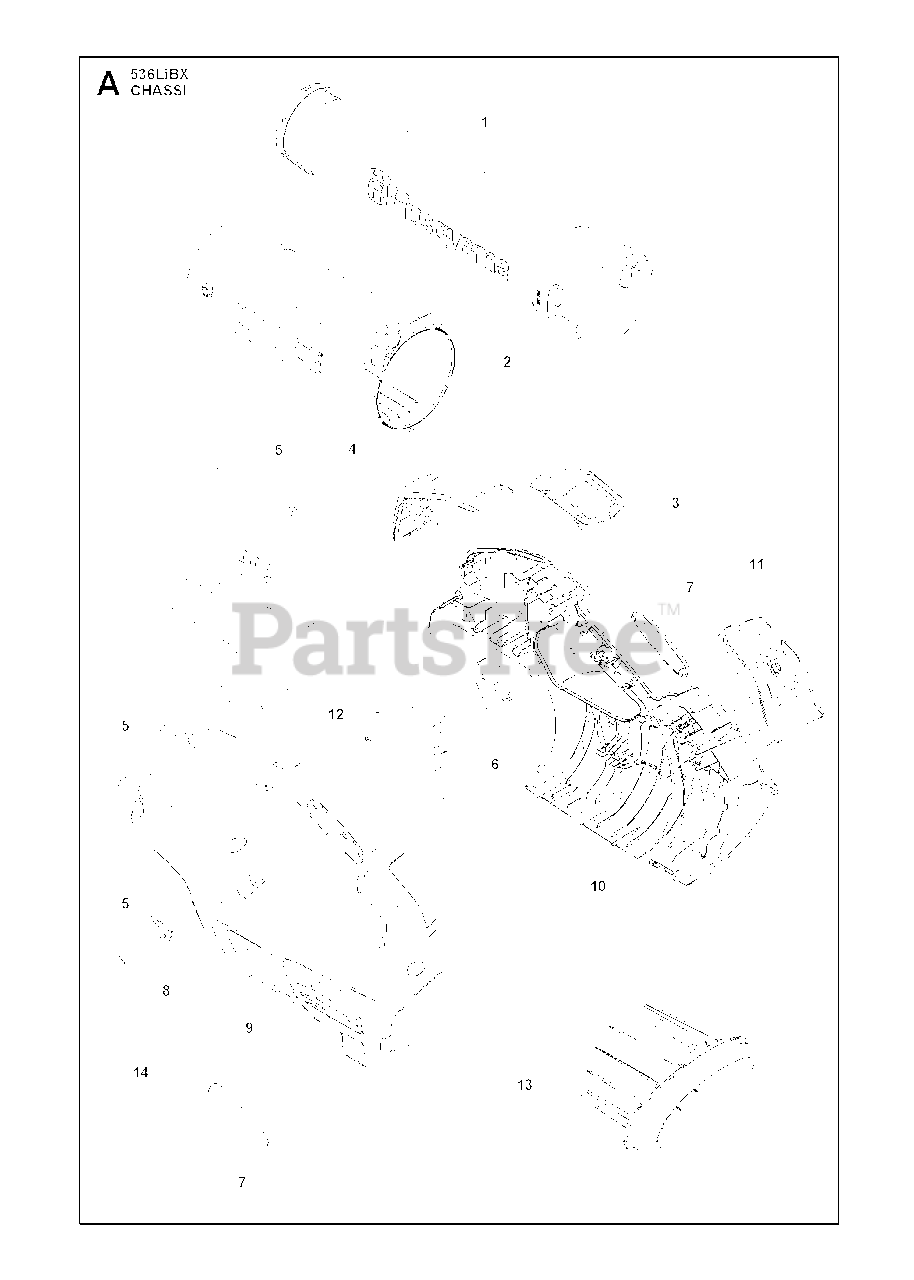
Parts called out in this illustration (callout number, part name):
1	TUBE ASSY NOZZLE 536LIBX
2	TUBE FAN OUTLET
3	FRAME KEYPAD
5	SCREW
6	THROTTLE CONTROL
7	HANDLE INSERT GREY
14	KIT EYELET
